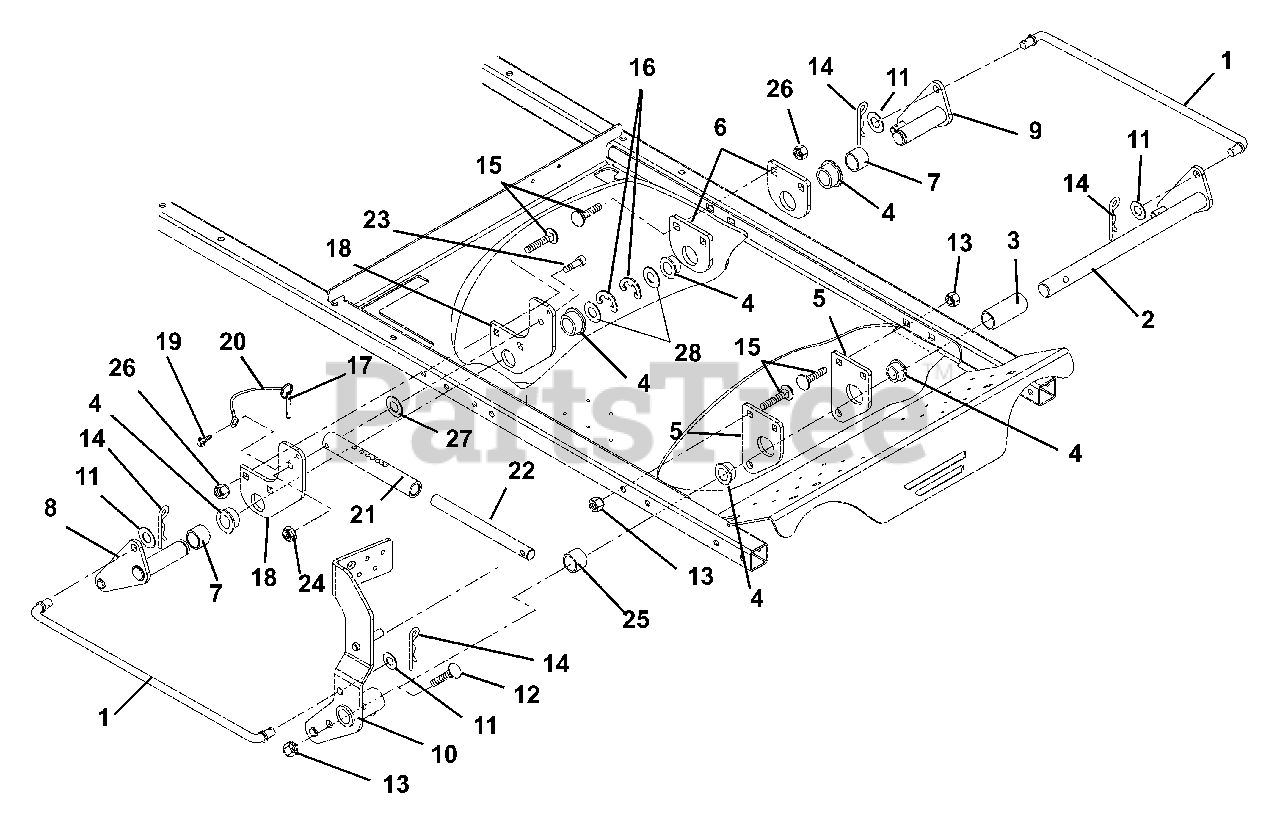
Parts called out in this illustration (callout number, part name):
1	ROD,DRAG LINK
2	WELDMENT,FRONT LIFT
3	BUSHING, FRONT
4	BSHG-FLG 1.000X1.12X.62X1.50BR
5	BRACKET, FRONT PIVOT
6	BRACKET,REAR PIVOT
7	BSHG-SPCR 1.032X1.250X.88 PM
8	WELDMENT, LIFT, REAR - RH
9	WELDMENT, LIFT, REAR - LH
10	WMT, FOOT PEDAL
11	@WSHR-FL-STL.531X1.06X.095YWZC
12	@BLT-HEX .38-16X2.00 GR5 YWZC
13	@NUT-LK-NYL-FLG .38-16 YWZC
14	PIN, HAIR, EXT - #16 YWZC
15	@BLT-RDHDSQNK .38-16X2.50 G5YZ
16	RG-RTNG .822X1.500X.050 TYP E
17	PIN, SPRING BALL .375OD X 1.50
18	MOUNT, REAR LIFT
19	@SCR-TAP .25-20X.37 HWH YWZ TR
20	CBL,HOOD
21	TUBE, LIFT STOP
22	ROD, LIFT
23	BLT, SKH SHLD .31-18X2.25
24	@NUT-LK-NYL-FLG .31-18 YWZC
25	BSHG, SPCR 1.032X1.25X.25 PM
26	@NUT-LK-TOP-FLG .38-16 YWZC
27	WSHR-FL-STL .390X.75X.125 YWZC
28	WSHR-FL-STL 1.12X1.500X.092 YZ
